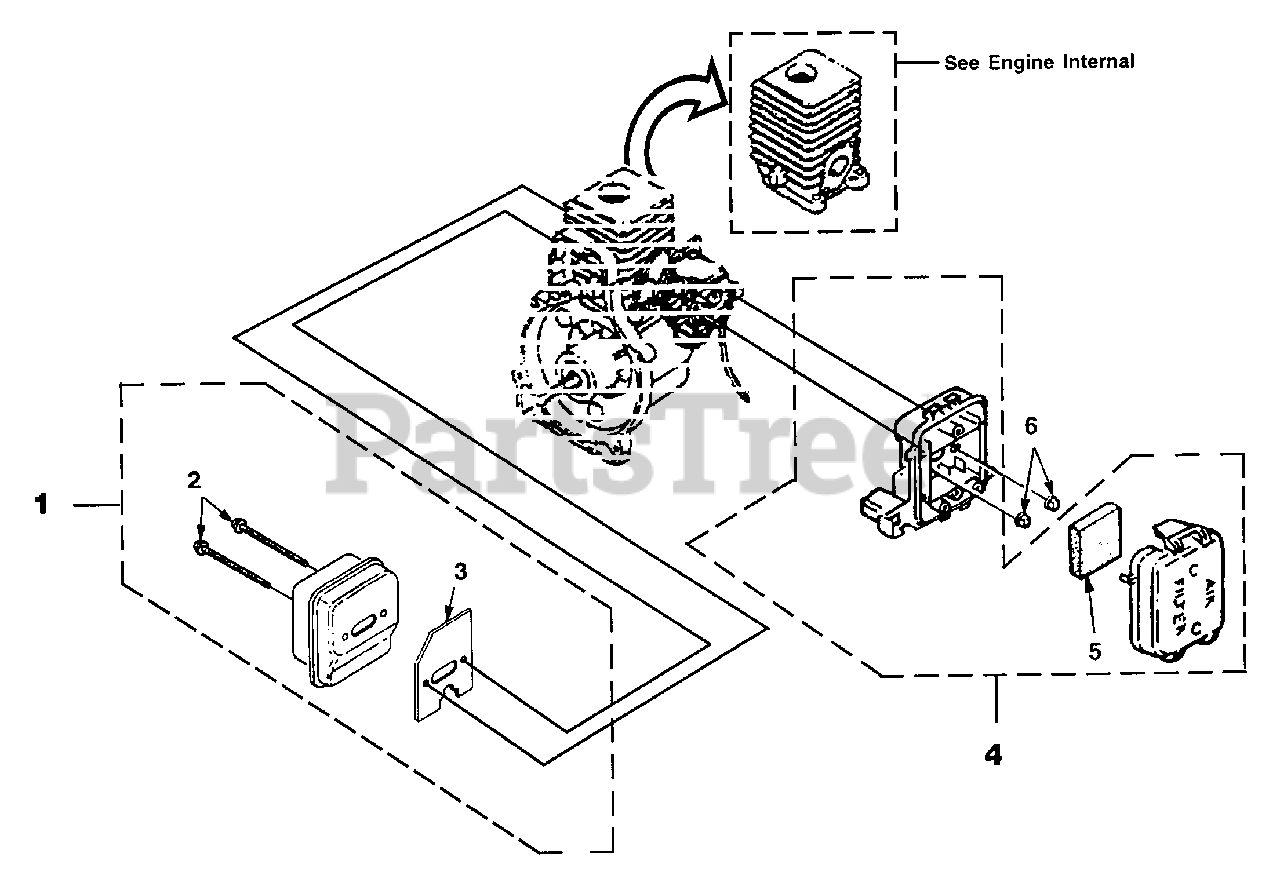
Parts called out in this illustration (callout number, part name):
1	MUFFLER COMPLETE
2	SCREW-Sems Hex (10-24 X 2 1/2")
3	GASKET-Muffler
4	AIR FILTER KIT
5	FILTER-AIR
6	NUT-Hex (10-24)
